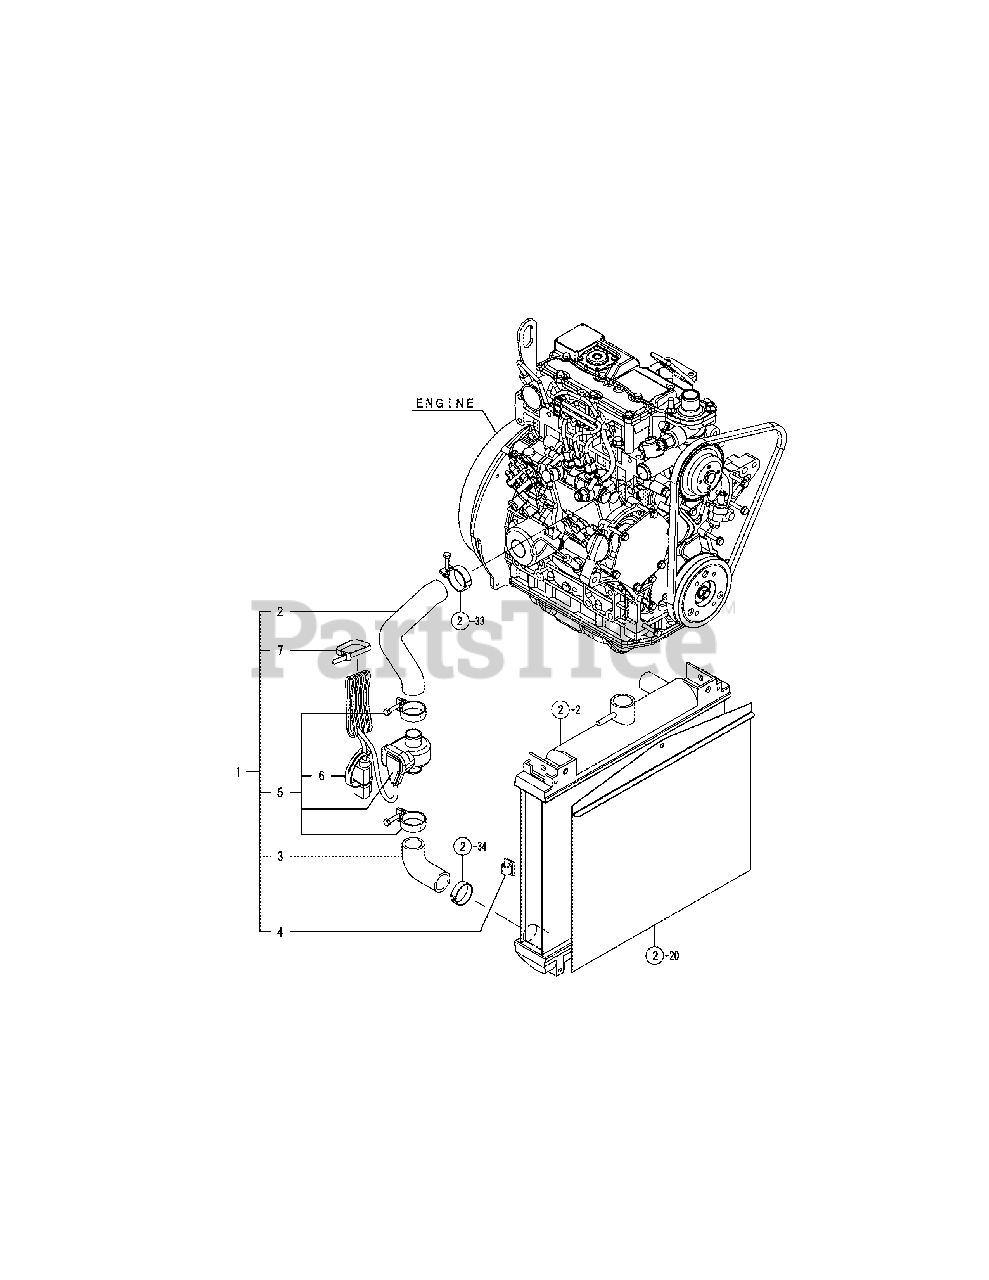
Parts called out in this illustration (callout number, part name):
1	Heater Kit, Radiator
2	Hose U,Cooling Water
3	Hose L,Cooling Water
5	Heater,Radiator Hose
6	Plug Protector
